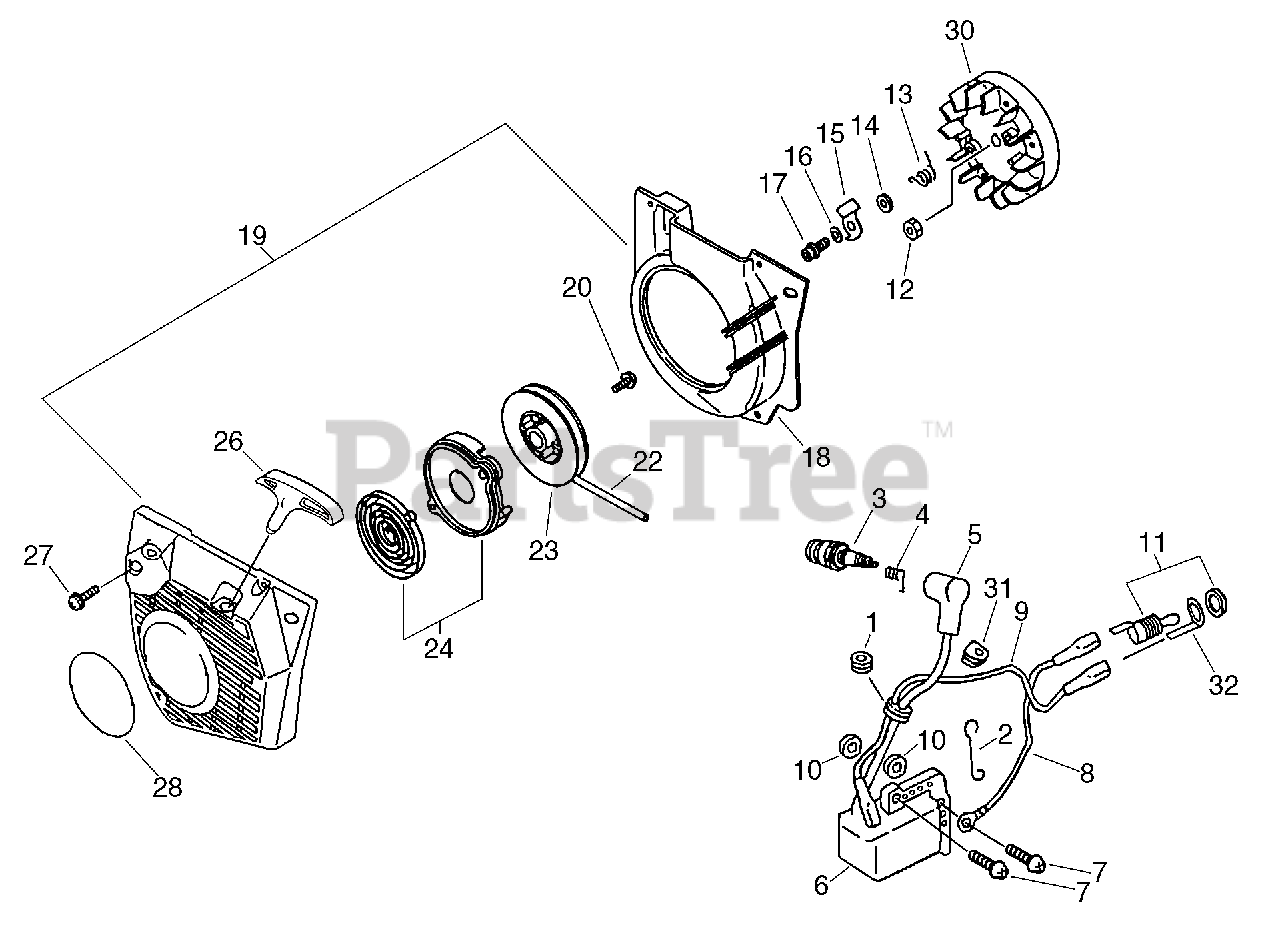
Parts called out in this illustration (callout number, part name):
3	SPARK PLUG -- BPMR-7A
4	TERMINAL, SPARK PLUG CAP
5	CAP, SPARK PLUG
6	COIL, IGNITION
7	SCREW - 5X25
8	LEAD - GROUND
9	LEAD - GROUND
11	IGNITION SWITCH ASSY
12	NUT - 8 -- FLANGE
13	SPRING, RETURN
15	PAWL, STARTER
16	WASHER - 5
17	SCREW - 5X12
18	COVER, FAN
19	STARTER CASE KIT
22	ROPE, STARTER
23	REEL, ROPE
24	REWIND SPRING KIT
26	GRIP, STARTER
27	SCREW - 4X16
28	LABEL - ECHO
30	FLYWHEEL
32	TERMINAL - GROUND
